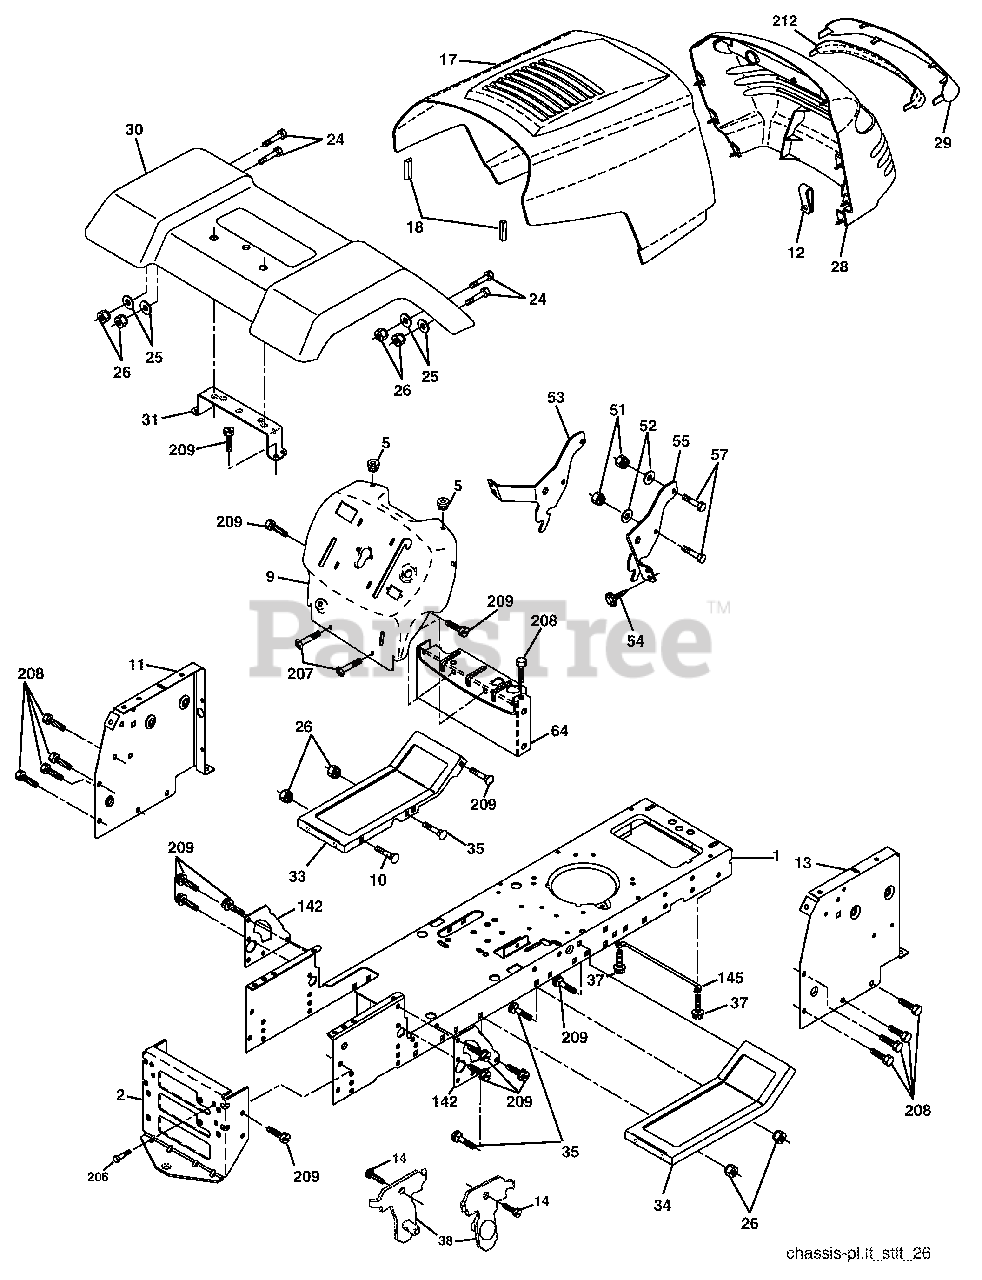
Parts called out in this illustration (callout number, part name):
1	Chassis
2	Drawbar
5	Bumper Hood/Dash
10	Bolt Rd Hd Sqnk. 3/8-16 Unc x 1
11	Panel Asm. Dash Lh
12	Clip Tinnerman Grile P/L
13	Panel Dash Rh
14	Screw Thdrol 3/8-16 x 1/2
17	Hood
18	Bumper Hood
24	Bolt Fin Hex 3/8-16 Unc x 1 Gr. 5
25	Washer 13/32 x 13/16 x 12 Ga.
26	Nut Lock Hex w/Insert 3/8-16 Unc
28	Grill/Lens Asm
29	Lens Grille
30	Fender Asm
31	Bracket Fender
33	Footrest LH
34	Footrest RH
35	Bolt Rd Hd Sht. Sqnk. 3/8-16 x 3/4
37	Screw Thdrol 5/16-18 x 1/2 Tyt
38	Bracket Asm. Pivot Mower Rear
51	Nut Lock Hex W/Ins. 1/4-20
52	Washer 9/32 x 7/8 x 16 Ga.
53	Bracket Grille LH
54	Screw Hex Wshd 8-18 x 7/8
55	Bracket, Grille RH
57	Bolt Fin Hex 1/4-20 x .75
64	Dash Lower
142	Plate Reinforcement
145	Rod Pivot Chassis/Hood
206	Bolt shoulder 5/16-18
207	Screw Thdrol 5/16-18 x 1/2
208	Screw Thdrol 3/8-16 x 1/2
209	Screw 3/8-16 x 3/4
212	Insert Lens Reflector
